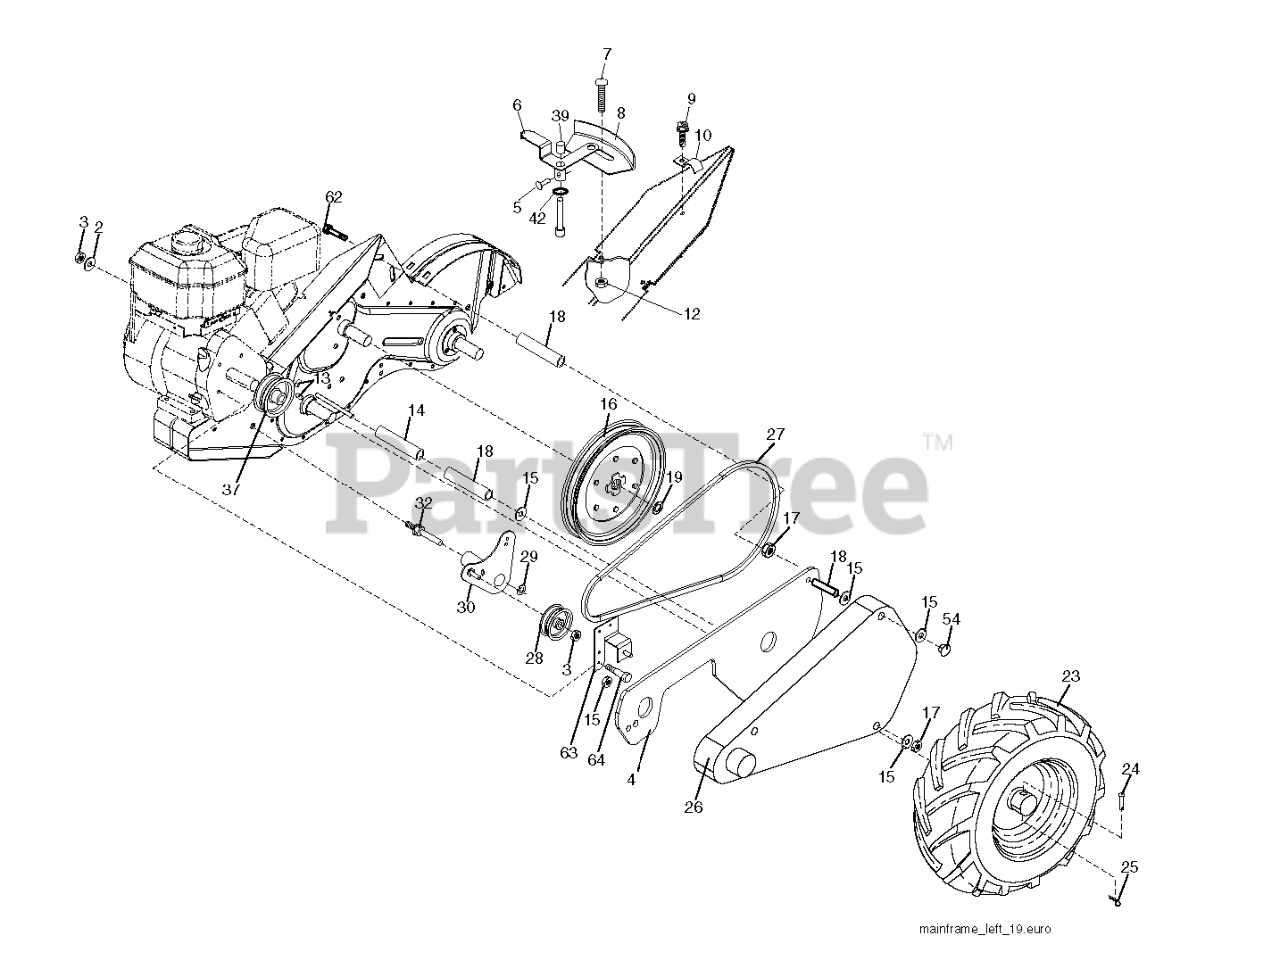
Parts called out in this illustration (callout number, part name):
2	WASHER, LOCK 3/8
3	NUT.HEX.3/8-16UNC
4	Shield, Inner Belt Guard RT
5	PIN.SPIROL.FLARED
6	LEVER ASM CRT
8	PANEL.INDICATOR.SHIFT.BLACK
9	TAPPING SCREW
10	CONDUIT.CLIP.PLATED
12	NUT
14	SPACER-SPLIT.327 X .42
15	WASHER
16	SHEAVE, TRANSMISSION
18	SPACER SPLIT
19	RETAINING RING LT
23	TIRE.16X4-8.CHEVRON.TILLER
25	SPRING TI
26	FOOTREST.PNT.LH
27	BELT, DRIVE
28	PULLEY-IDLER TI
30	BRACKET.ASM.IDLER.BLACK
32	SHAFT, IDLER ARM
37	SHEAVE, ENGINE
39	CAP.PLUNGER.BLACK
62	BOLT 5/16-18X4 1/2
63	Bracket Asm Guard
